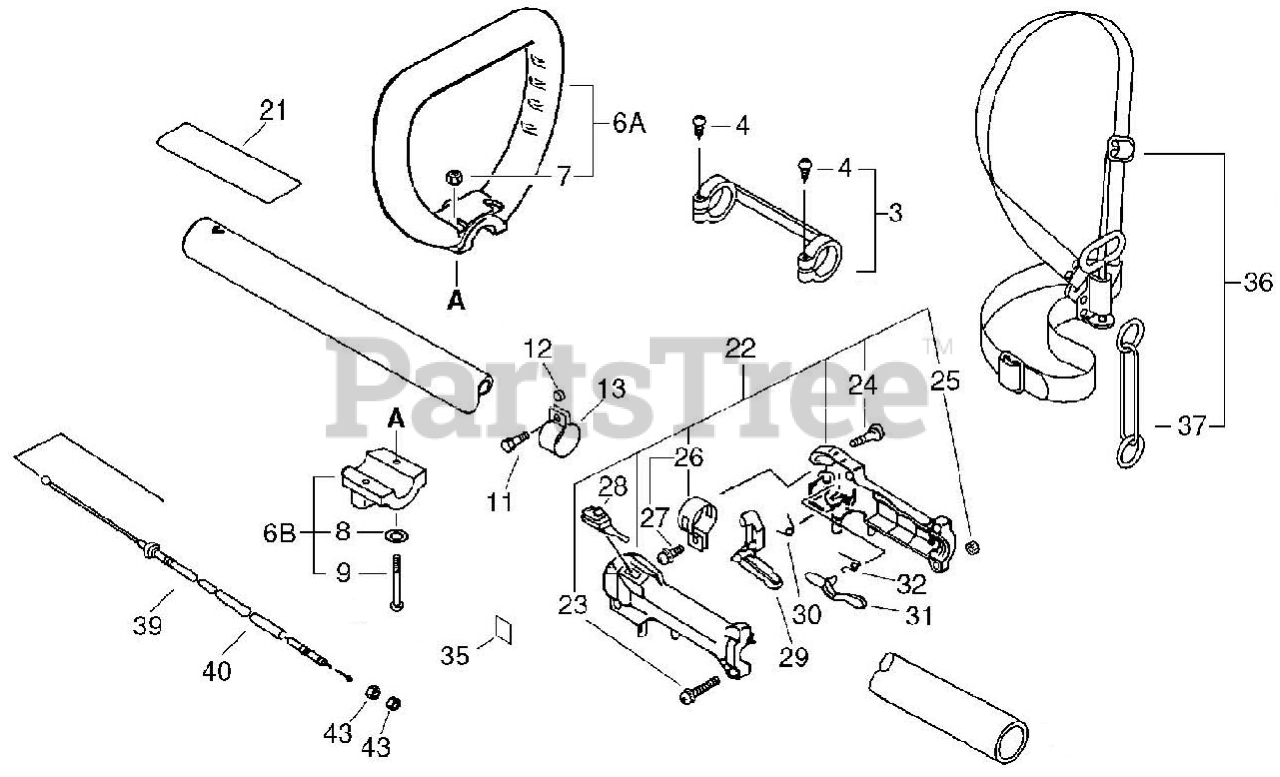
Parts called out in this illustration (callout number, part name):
3	COLLAR
4	SCREW 4×25
6	LOOP HANDLE ASSY
8	WASHER, FLAT 5.5×10×0.8
9	SCREW 5×40
11	BOLT 5×18
12	SPACER, GUARD
21	LABEL - CAUTION - ISO
22	CONTROL HANDLE KIT
23	SCREW 5×25
24	SCREW, TAPPING 4×18
26	CLAMP KIT
27	SCREW 5×12
28	SWITCH, IGNITION
29	CONTROL, THROTTLE
30	SPRING, TORSION
31	LOCKOUT, THROTTLE
32	SPRING, THROTTLE LOCKOUT
35	LABEL - STOP
36	HARNESS ASSY
39	CABLE, THROTTLE
